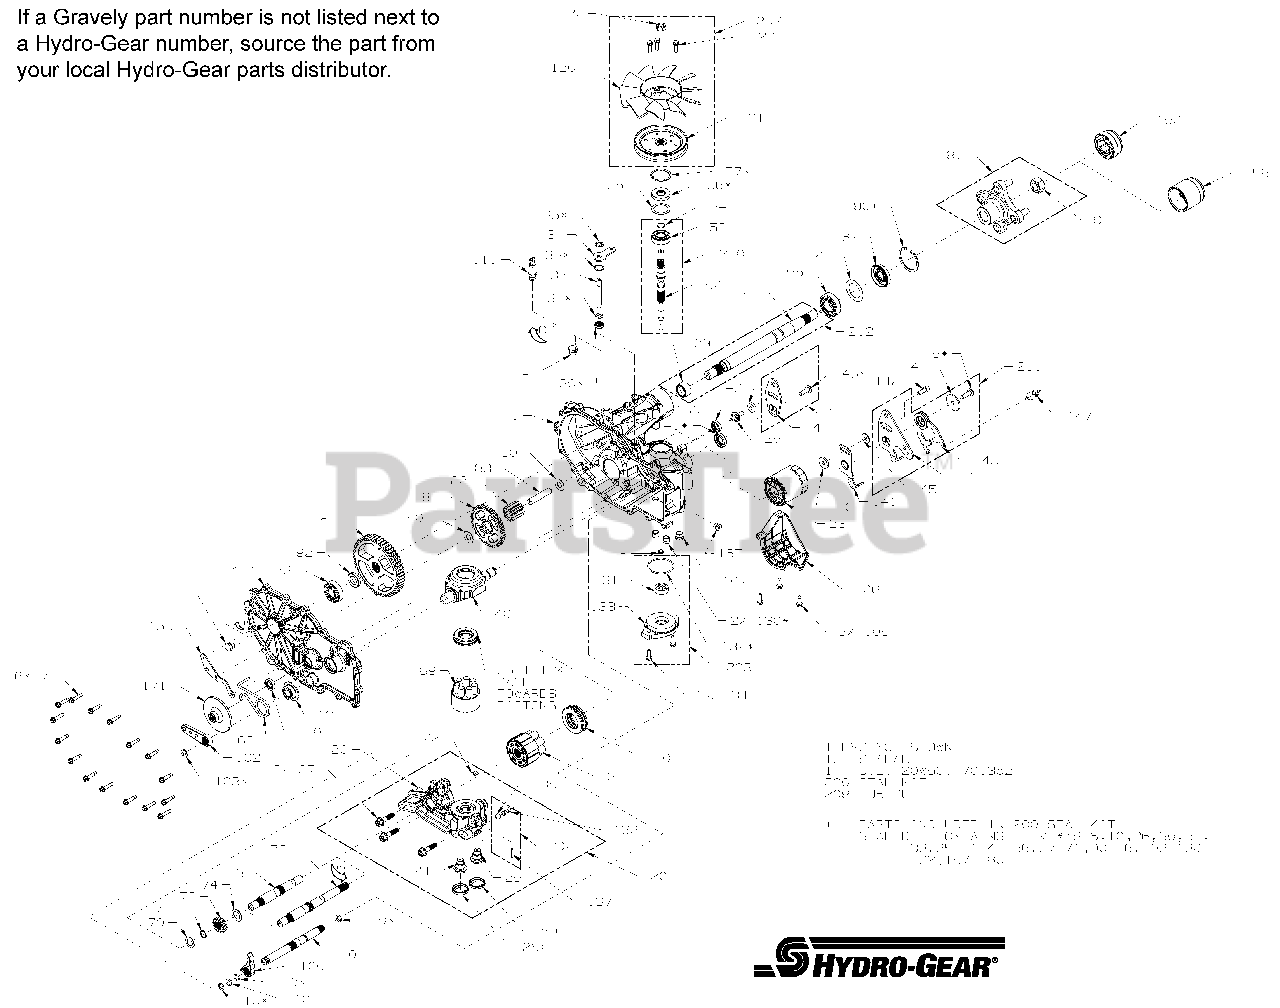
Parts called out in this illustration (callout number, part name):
1	KIT, HOUSING, MAIN, LH, CHRG, CNTL
2	KIT, COVER, SIDE, LH
7	SCREW,HEX WASHER 1/4-20X1.125
13	SEALANT TUBE 10.1OZ.
22	PLATE, BYPASS
23	OIL FILTER, TRANSMISSION
26	SEAL, PLUG 1.375 X .250
30	SEAL, LIP .375X.75X.25
31	RING. RETAINING
32	ROD, BYPASS
33	RING, RET .750
34	HG BYPASS ARM (52370)
35	RING, RTNG .
40	TRUNNION, SWASHPLATE
41	SEAL, LIP 18X32X7
45	WASHER
46	TWHCS 5/16-24 X 1.00
55	WASHER 1.23X1.56X.04
56	SEAL, LIP 17X40X7
57	RING, RET 1.56 INT
60	HG THRUST BEARING (51462)
64	HG 16CC CYLINDER BLOCK (71579)
65	BEARING. THRUST 30 X 52 X 13
69	ASSY, BLOCK 7 PISTON
70	WASHER .63X1.0X.05
71	RING, RET 62 EXT
72	GEAR, 13T, STEEL
73	SHAFT, MOTOR
74	WASHER .71 X 1.16 X .04
80	WASHER .5X1.0X.032
82	GEAR, 11T, STEEL
83	JACK SHAFT (PIN)
90	RING, RETAINING
95	BEARING, BALL 25.4 X 52 X 15
96	SEAL, LIP
97	HUB, HYDROGEAR P/N 71691
99	NUT, HEX, LOCK 3/4-16
100	PAWL, BRAKE
101	KIT, BRAKE SHAFT
102	HG ACTUATING KIT HANDLE
103	RING, RETAINING
105	HFHCS 1/4-20X.75
106	HG FILTER GUARD LH (52247)
111	KIT, FITTING 1/2 BEADED 9/16
120	FAN, 7.0 W/ INSERT
121	DISC, PULLEY, CUPPED, 4.5 INCH
122	NUT, HEX 1/2-20 PATCH
124	HUB, PULLEY
130	TUBE, CONNECTING
131	GEROTOR
132	O-RING HYDROGEAR 52250
134	HFHCS 1/4-20X.75
140	SPACER
141	ARM, NEUTRAL LEFT
142	SHCS 5/16-24X1 PATCH
147	SPRING, EXTNSN RTN - 34 LBS
156	CAP, AXLE
157	KIT, GEROTOR SEAL
159	SPRING, TORSION, CW
164	SPACER
200	KIT, SEAL
201	KIT, CENTER SECTION, LH, CHRG
202	KIT, CHARGE RELIEF
203	KIT, CHARGE PUMP 71411
207	PULLEY/FAN KIT HG P/N 71694
209	HUB PULLER 4 BLT HYDGEAR 71459
210	INPUT SHAFT 2800 HYDGEAR 71442
211	TRN KIT HRDROGEAR P/N 71599
212	KIT, SHAFT, AXLE
